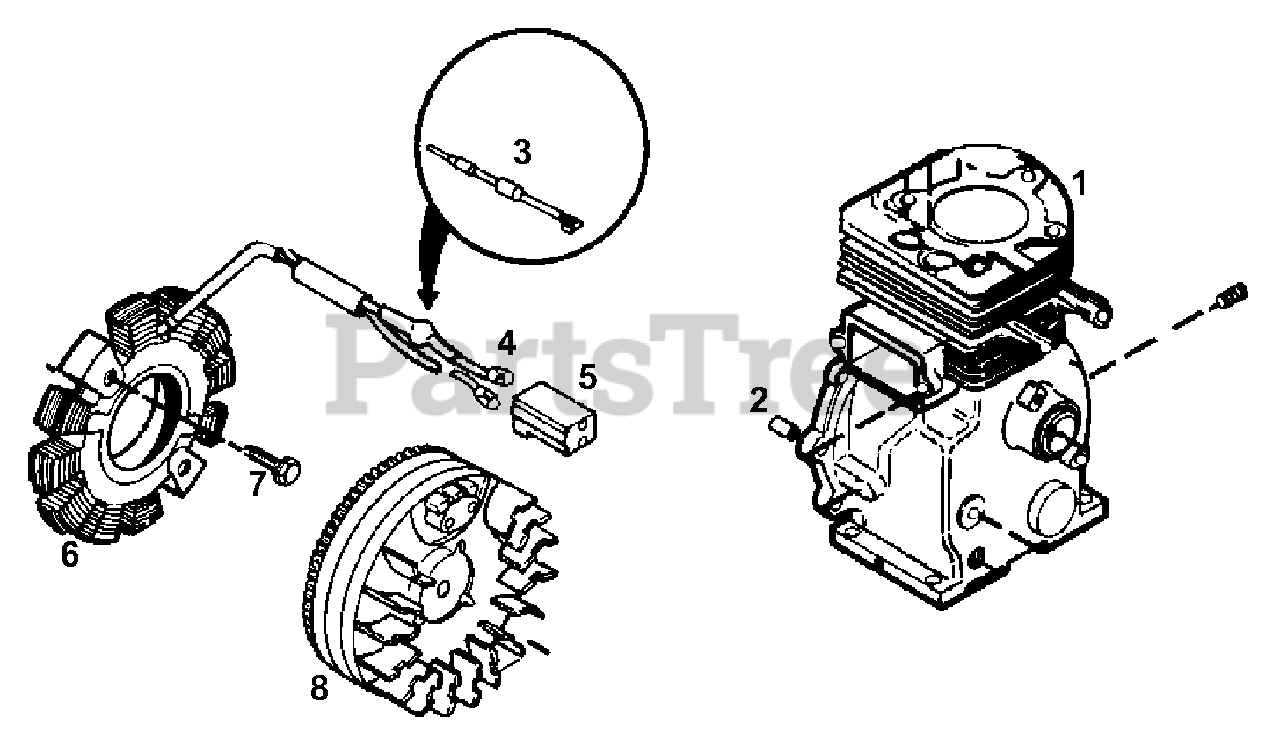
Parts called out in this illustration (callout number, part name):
2	Dowel Pin
5	Connector Body
6	Alternator Coil
7	Screw, 1/4-20 x 3/4"
8	Flywheel (W/Ring Gear)
